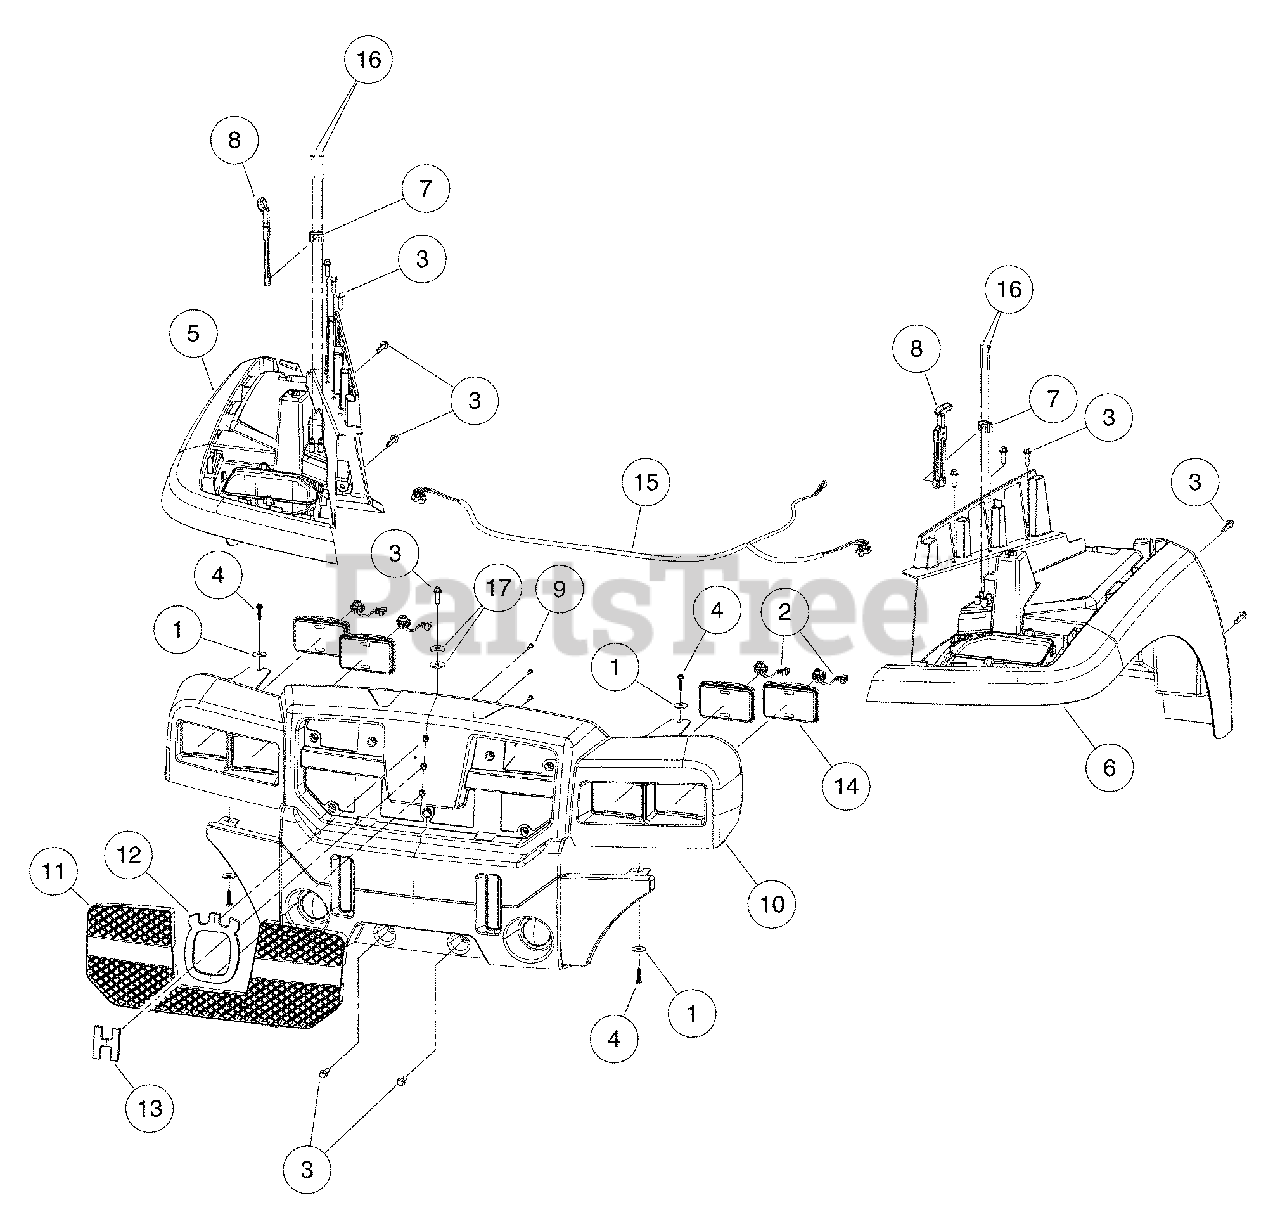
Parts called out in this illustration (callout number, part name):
1	Washer, 5/16 Type B Flat
2	Connector Harness Assembly, Headlight
3	Screw, M8X1.25X30, Hex
4	Screw,m6,torx,interlock,thread
5	Fender, Front, Pass, AWD
6	Fender, Front, Drv, AWD
7	Bracket, Latch, Draw
8	Latch, Draw, Hood
9	Screw, D50x16, Torx PN Hd PT
10	Fascia, Husqvarna
11	Grill, Husqvarna
12	Emblem, Husqvarna, Outer
13	Emblem, Husqvarna, Inner
14	Headlamp, 3x5 Rectangular
15	Harness, Bct/huv Restyle Headlight
16	Screw, #8x2.00 AB Thd, Hex Hd
17	Washer, 3/8 Type B Flat
